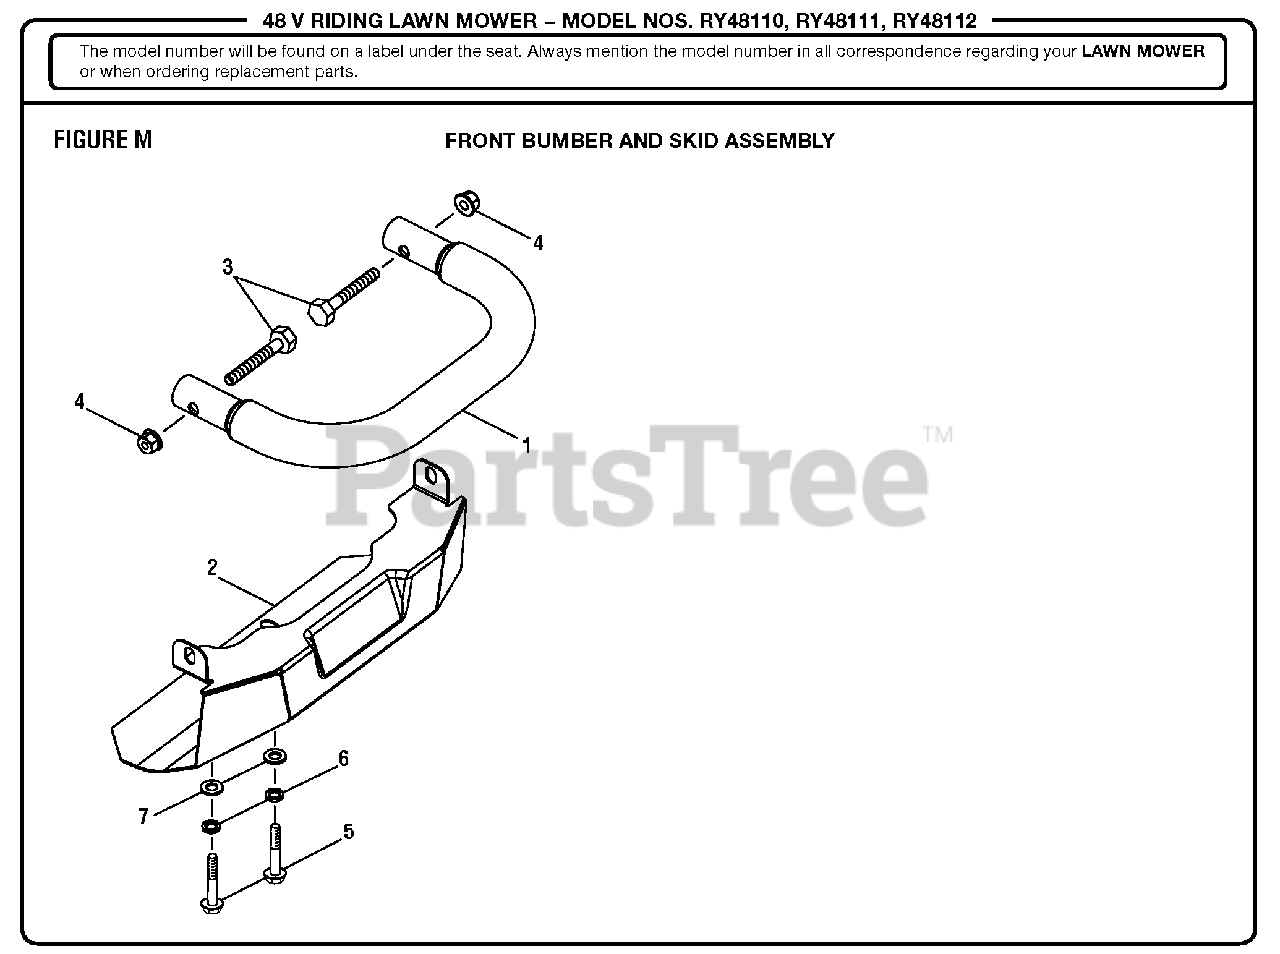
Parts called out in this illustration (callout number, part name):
1	Mower Bumper Tube
2	Front Bumper Cover
3	Shoulder Bolt (M8 x 50 mm)
4	Lock Nut (M8 x 1.25)
5	Shoulder Bolt (M8 x 45 mm, Hex Flange Hd.)
6	Lock Washer (8 mm)
7	Washer (OD16 x ID8.4 x 1.6t)
